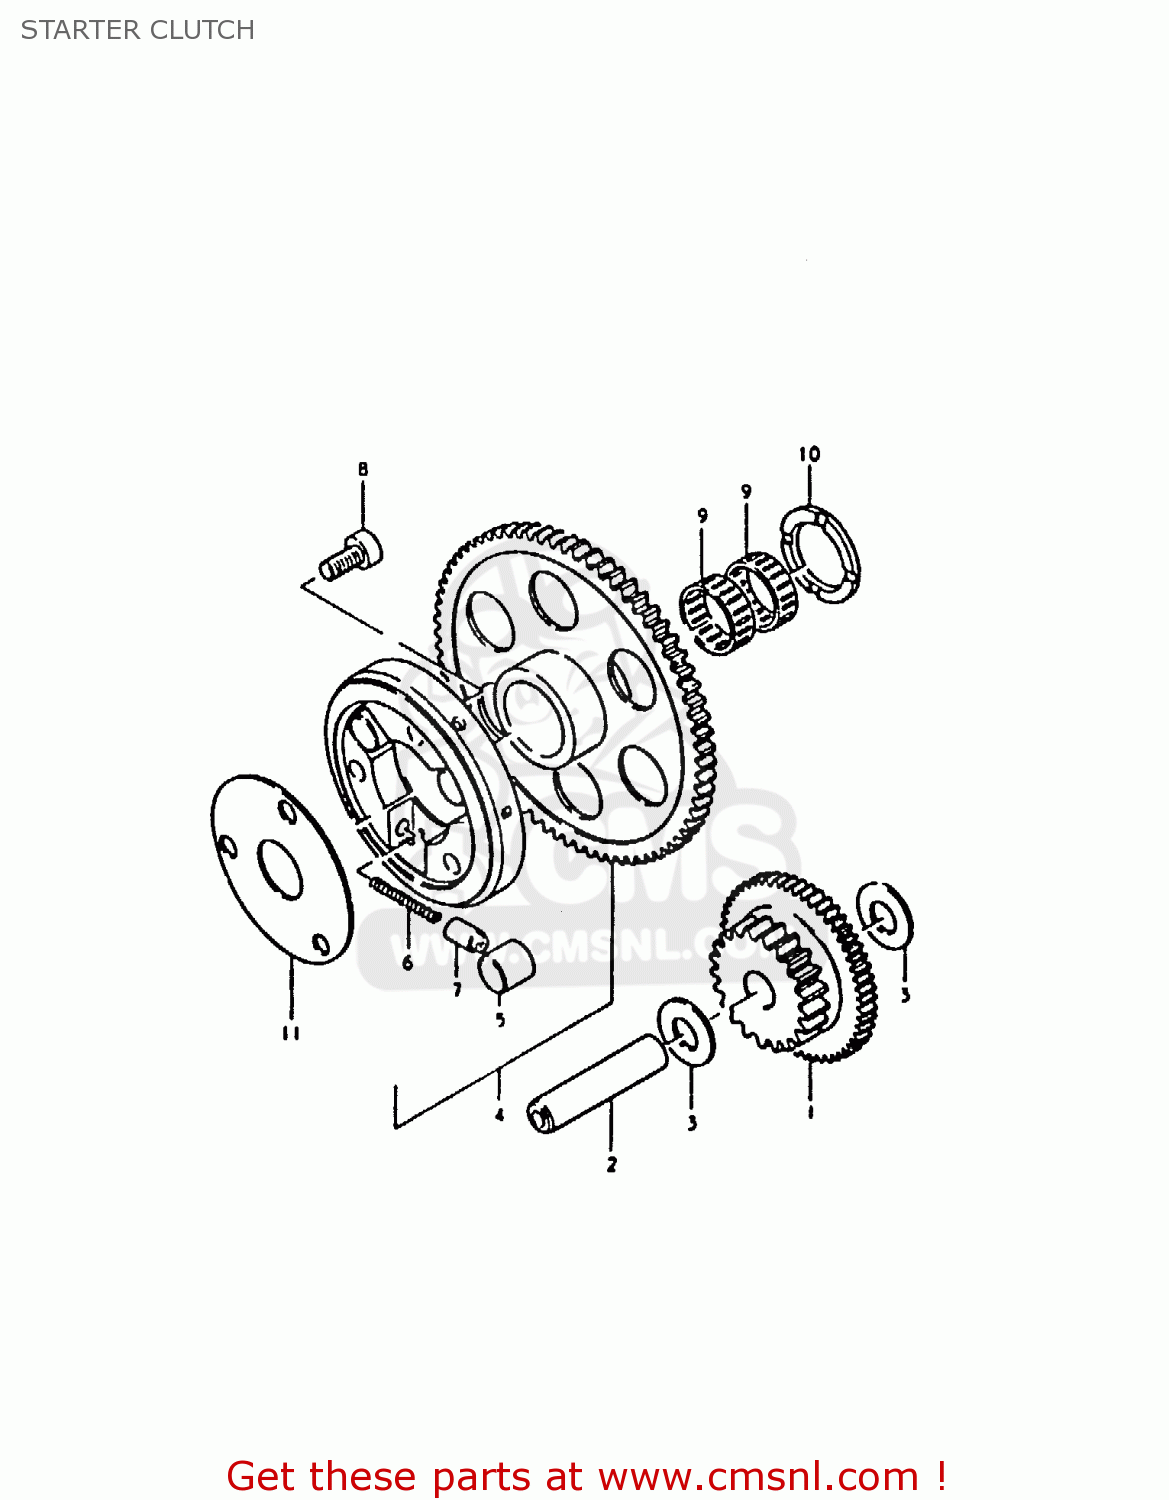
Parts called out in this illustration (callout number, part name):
1	GEAR,STARTER IDLE
2	PIN(7.4X13X56)
3	WASHER(13.3X25X0.85)
4	CLUTCH SET,STARTER
5	ROLLER(15X13)
6	SPRING
7	PIECE,PUSH
8	BOLT
9	BEARING(25X29X9.9)
10	WASHER(25X38X2.5)
11	SHIM,STARTER CLUTCH HUB
